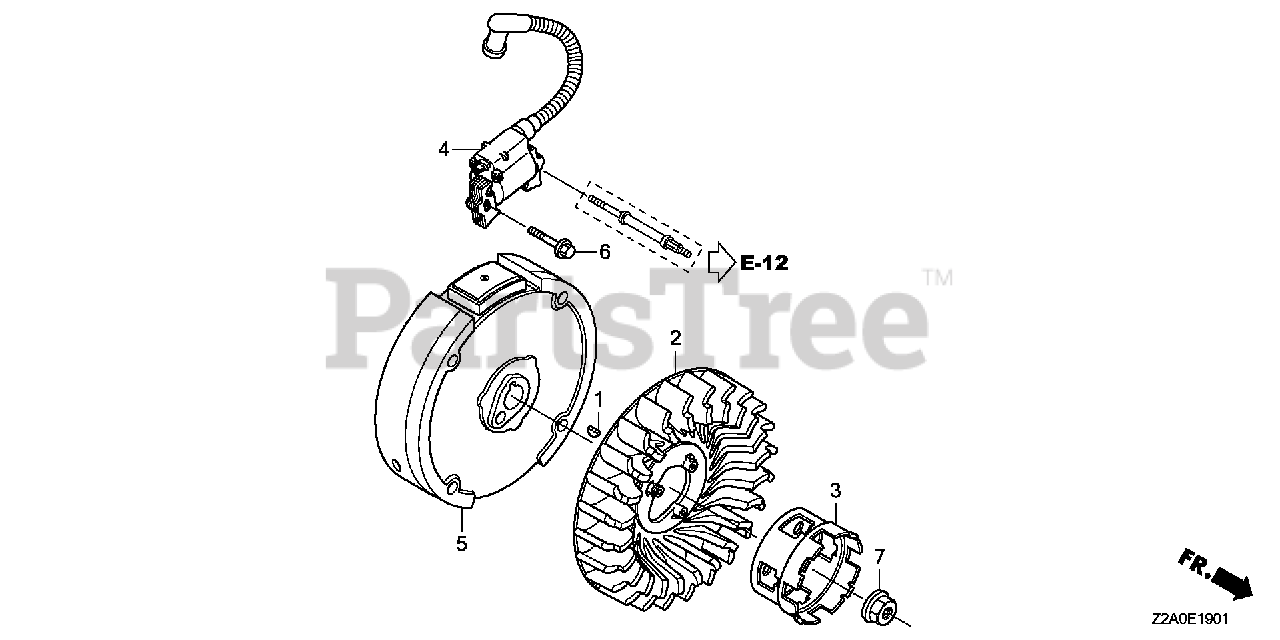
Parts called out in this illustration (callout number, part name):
1	KEY, SPECIAL WOODRUFF (25X18)
2	FAN, COOLING
3	PULLEY, STARTER
4	COIL ASSY., IGNITION (TOYO)
5	FLYWHEEL
6	BOLT, FLANGE (6X23) (CT200)
7	NUT, SPECIAL (14MM)
